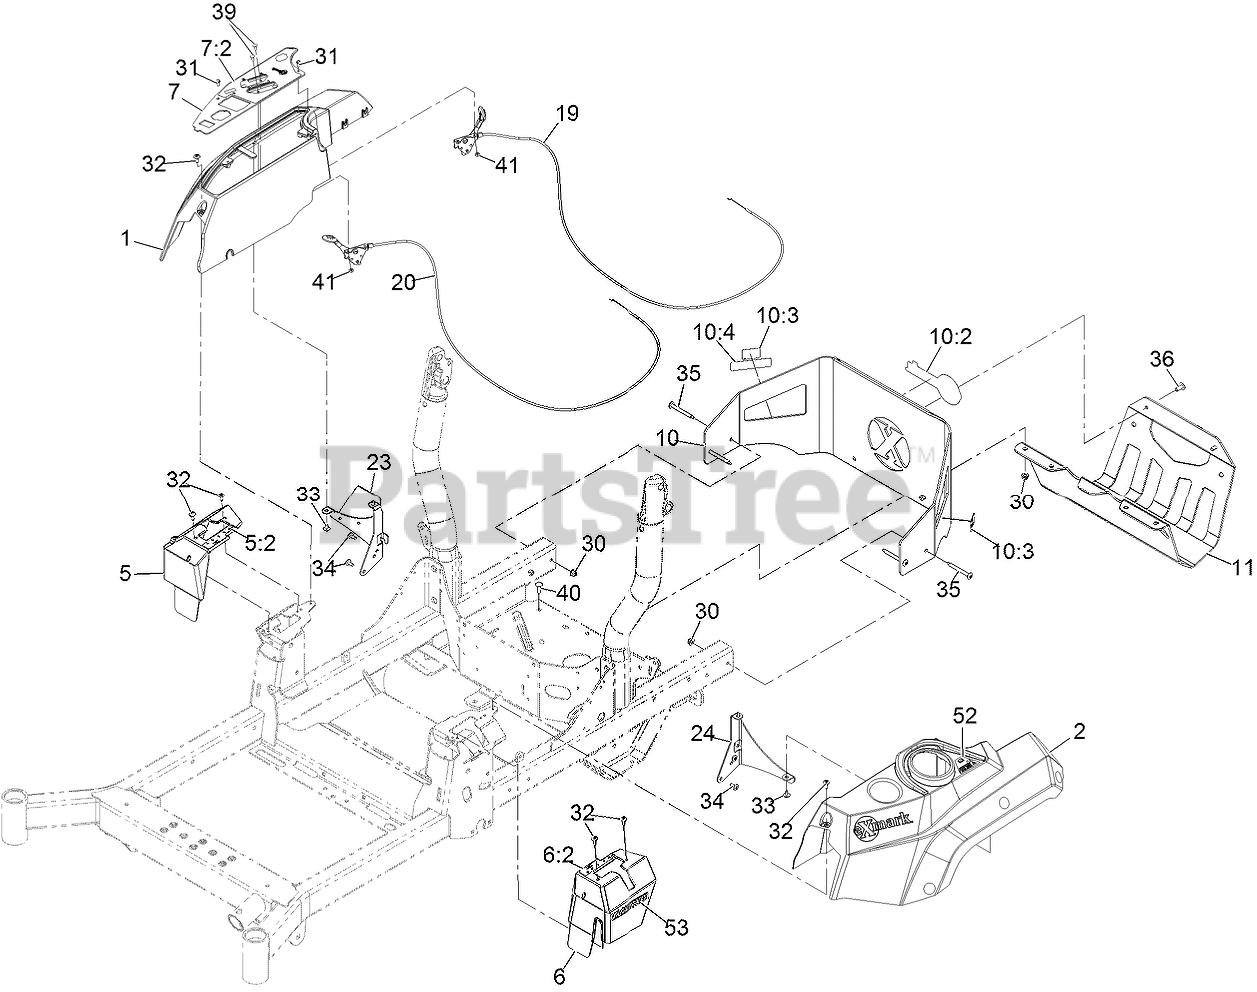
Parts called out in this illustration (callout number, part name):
1	CONSOLE, RH
2	CONSOLE, LH
5	COVER-CONTROL, MOTION (RH
5:2	Decal-Control, Motion (RH)
6	COVER-CONTROL, MOTION (LH
6:2	Decal-Control, Motion (LH)
7	ASM-Control Panel W/Exmark Decal
7:2	DECAL-CONTROL PANEL
10	REAR GUARD ASM
10:2	DECAL, EXMARK LOGO
10:3	DECAL-WARNING
10:4	DECAL-ARRESTOR, SPARK
11	Guard-Muffler [black]
19	CABLE-CONTROL, CHOKE
20	CABLE-CONTROL, THROTTLE
23	SUPPORT-CONSOLE, RH
24	BRACKET-CONSOLE, LH
30	NUT-HF, NI
31	SCREW-HWH
32	SCREW-SHOULDER
33	SCREW-TORX
34	SCREW-TORX
35	SCREW-TORX
36	SCREW-TORX
39	BOLT-CARR
40	SCREW-CARR
41	NUT-LOCK, NI
52	DECAL-FILL, FUEL
53	DECAL-E-SERIES
